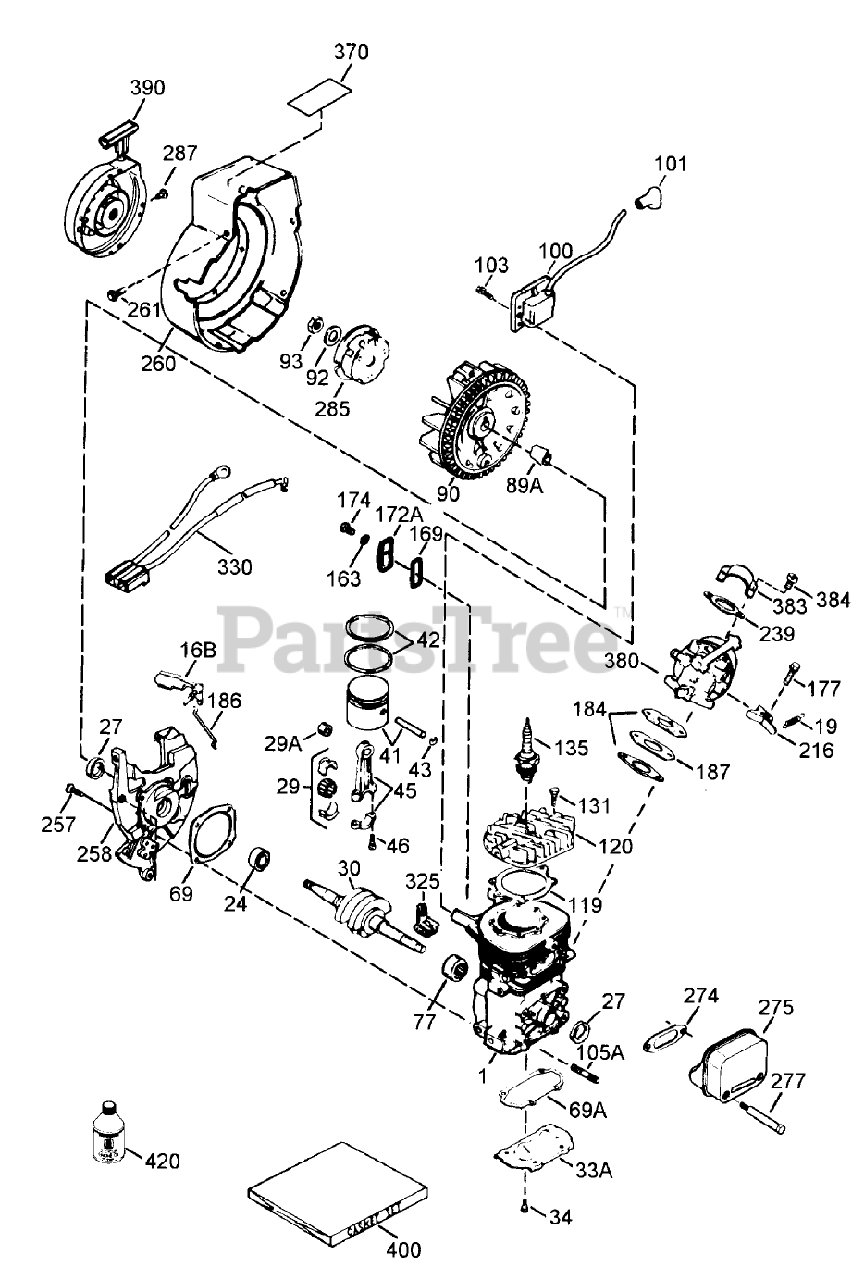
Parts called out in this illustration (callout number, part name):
1	Block Ass-y-Cylinder (Order short block if replacement is required)
16B	Vane-Air
19	Spring-Extention
24	Bearing-Ball
27	Seal-Oil
29	Needle Bearing and Liner Set (37 Needles)
29A	Bearing-Cartridge
30	Crankshaft
33A	Plate-Cover
34	Screw (T-25, 10-24 x 1/2)
41	Piston (Incl. Ref. #43)
42	Ring Set
43	Ring-Retaning
45	Rod Assy.-Connecting (Incl. Ref. #3, 3A 3B)
46	Bolt-Rod, Connecting
69	Gasket-Cover, Cylinder
69A	Gasket-Plate, Cover
77	Bearing-Cartridge
89A	Blade (20 inch)
90	CARB BODY S
92	Washer-Belleville
93	Nut-Flywheel
100	Solid State
101	Cover-Spark Plug
103	Screw
119	Gasket-Head, Cylinder
120	Head-Cylinder
131	Screw (T-30, 1/4-20 x 3/4)
135	Spark Plug-Resistor (R C J 8Y)
163	Washer
169	Cover-Compression, Release
172A	Cover-Release, Compression
174	Screw (T-25, 10-24 x 1/2)
177	Screw (5/32 Allen, 1/4-20 x 1)
184	Gasket-Carburetor
186	Governor-Link
187	Spacer
216	Lever-Adjusting, Rpm
239	2060A77 WIZARD ROTA
257	Screw (T-30, 1/4-20 x 5/8)
258	Base Ass-y-Blower Housing (Incl Ref. #20)
260	Housing-Blower
261	Screw (1/4-20 x 1/2)
274	Gasket-Exhaust
275	Muffler (Incl. Ref. #274 277)
277	Screw (1/4-20 x 2-3/4)
285	Cup-Starter
287	Screw (8-32 x 21/64)
325A	Clip-Wire
330	Harness-Wire
370	Decal-Warning
380	Carburetor (Incl. Ref. #184A)
383	Baffle-Carburetor
384	Screw
390	Rewind Starter
400	Gasket Set
422	2-Cycle Oil (8oz)
